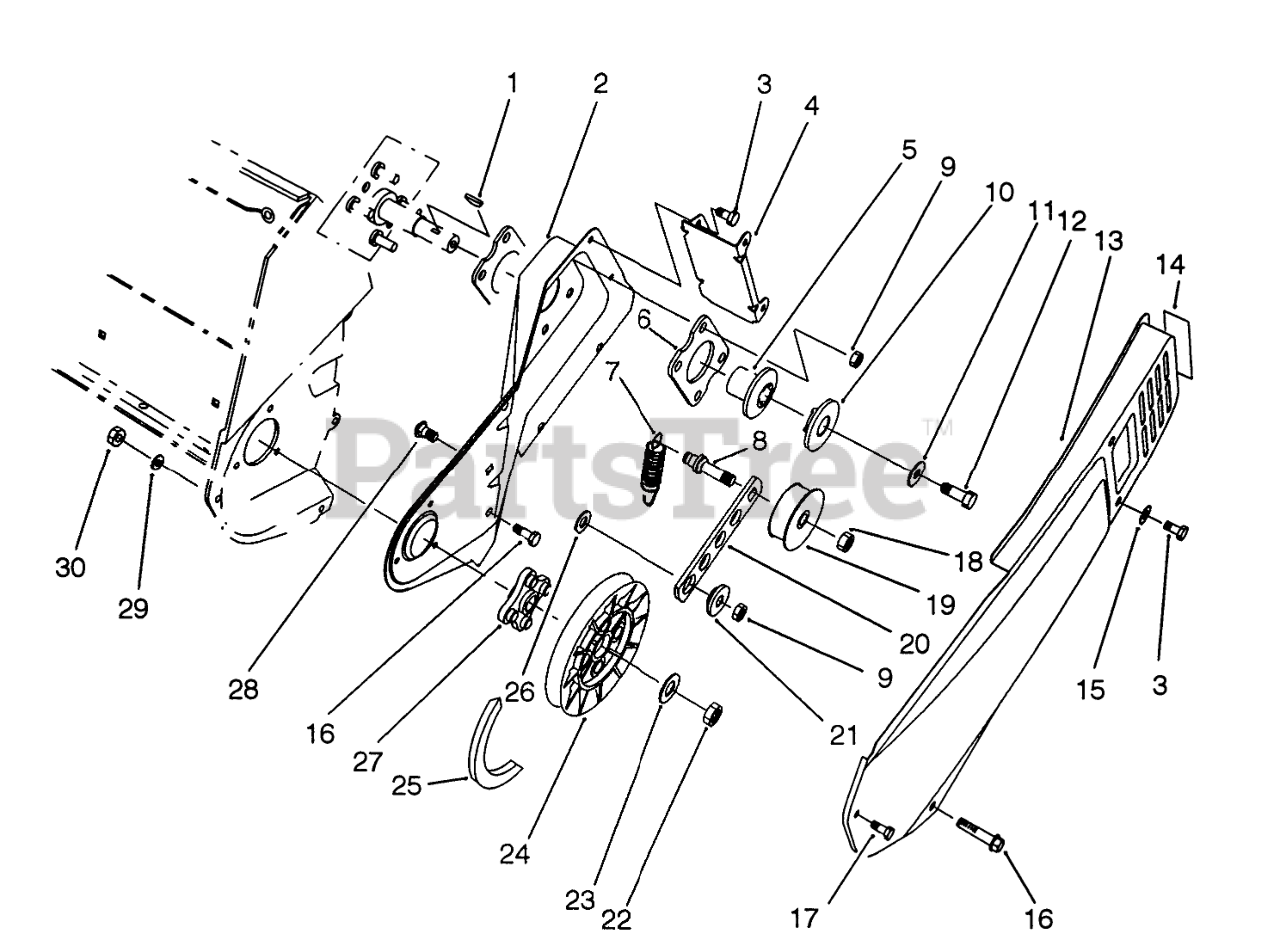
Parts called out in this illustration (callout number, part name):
1	KEY-WOODRUFF
2	Sideplate-LH
3	SCREW-HWH
4	Bracket-Cover
5	Hub-HALF SHEAVE
6	Plate Engine
7	SPRING-EXTENSION
8	PIN-IDLER
9	NUT-LOCK, NI
10	CAP-HALF SHEAVE
11	WASHER-FLAT
12	SCREW-HH
13	Cover-Belt
14	Decal
15	WASHER-FLAT
16	SCREW-PLASTIC
18	NUT-LOCK, NI
19	PULLEY-IDLER
20	ARM-IDLER
21	BUSHING-IDLER
22	NUT-LOCK, NI
23	WASHER-FLAT
24	PULLEY-DRIVEN
25	V-BELT
26	WASHER
28	SCREW-CARR
29	WASHER-FLAT
30	NUT-LOCK, NI
